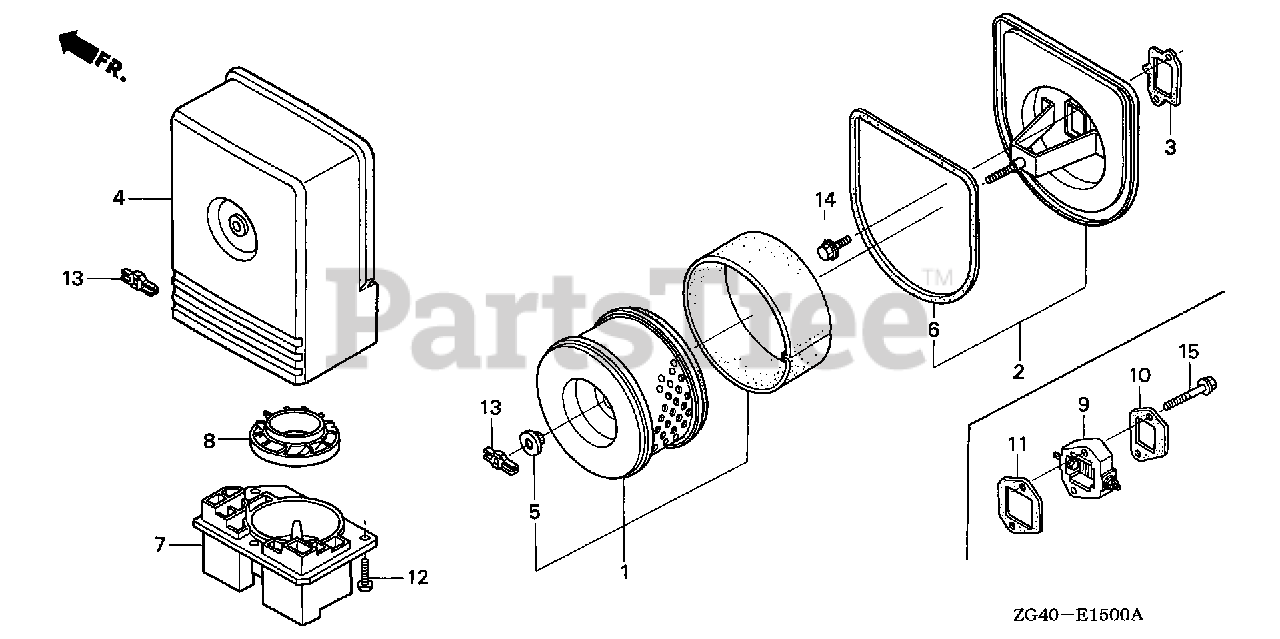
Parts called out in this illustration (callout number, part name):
1	ELEMENT, AIR CLEANER
2	HOUSING, AIR CLEANER
3	GASKET, AIR CLEANER (NON-ASBESTOS)
4	COVER, AIR CLEANER
5	GROMMET, AIR CLEANER
6	GASKET, AIR CLEANER HOUSING
7	CASE, PRE CLEANER
8	GUIDE, PRE AIR CLEANER
12	SCREW, PAN (5X16.5)
13	NUT, AIR CLEANER COVER (DACRO COATING)
14	BOLT, FLANGE (8X22)
